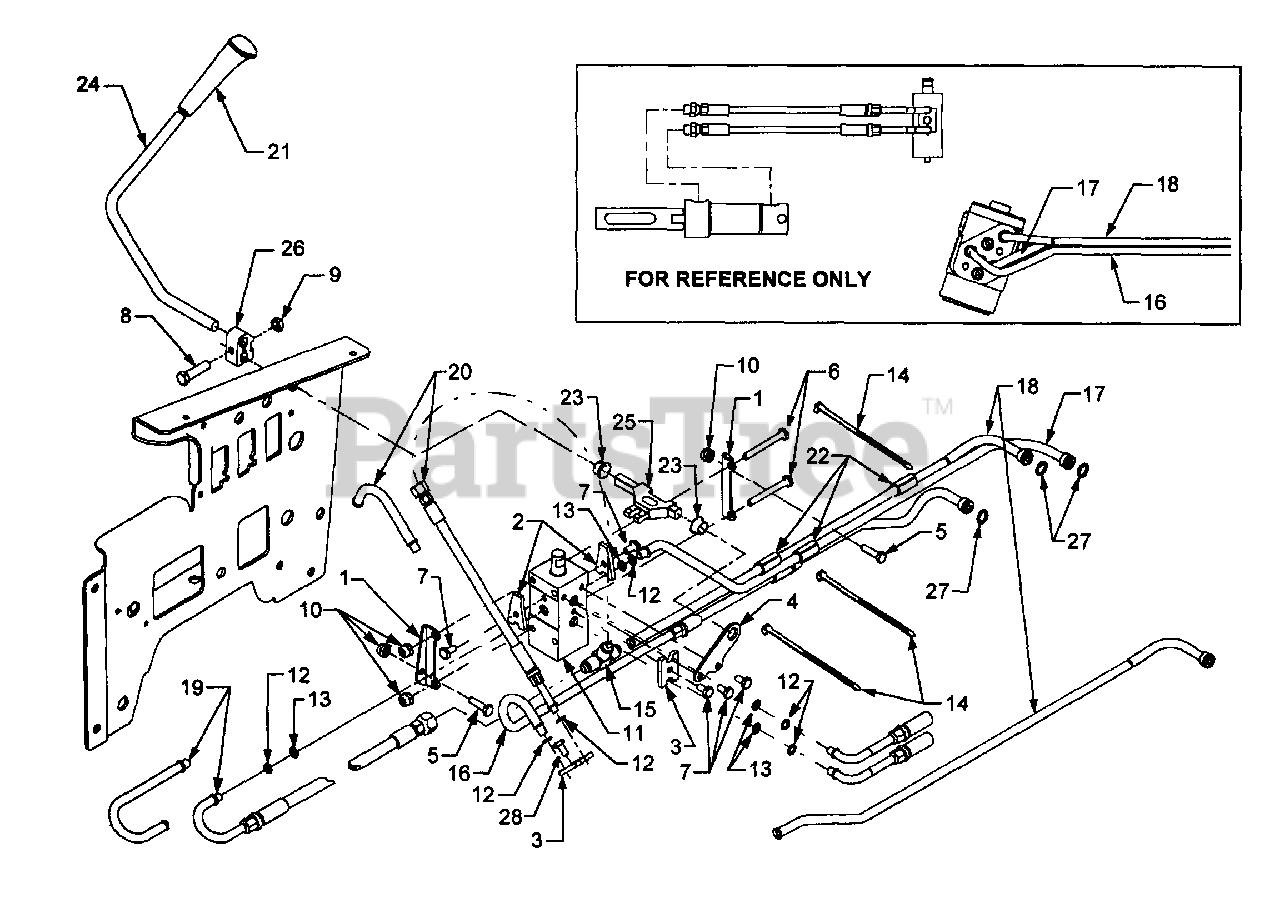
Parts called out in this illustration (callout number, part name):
1	Bracket, Valve Mounting
2	Clamp, Side Valve
3	Clamp, Double Valve
5	Screw, Hex Cap 1/4-20 x 1.0 GR5
6	Screw, Hex Cap 1/4-20 x 2.25 GR5
7	Screw, Hex Cap 1/4-20 x .50 GR5
8	Screw, Hex Cap 5/16-18 x 1.375 GR5
9	Nut, Hex Insert Lock, 5/16-18
10	Nut, Hex Flange Lock, 1/4-20
11	Valve, Hydraulic
12	O-Ring, Backup
13	O-Ring
14	Cable Tie
15	T-Fitting, 9/16-18 Thrd.
16	Tube, Hydraulic (Pump to Strng)
17	Tube, Hydraulic (Aux. from Strng)
18	Tube, Hydraulic (Strng Return)
19	Tube, Hydraulic (Aux Return)
20	Tube, Hydraulic (Return to Pump)
21	Knob, Lift
22	Rubber Spacer
23	Bearing, Nylon Flange
24	Handle, Center Lift Valve
25	Link, Lift
26	Clamp, Handle
27	O-Ring, .426 x .566 x .070
28	Screw, Hex Cap 1/4-20 x .62 GR5
